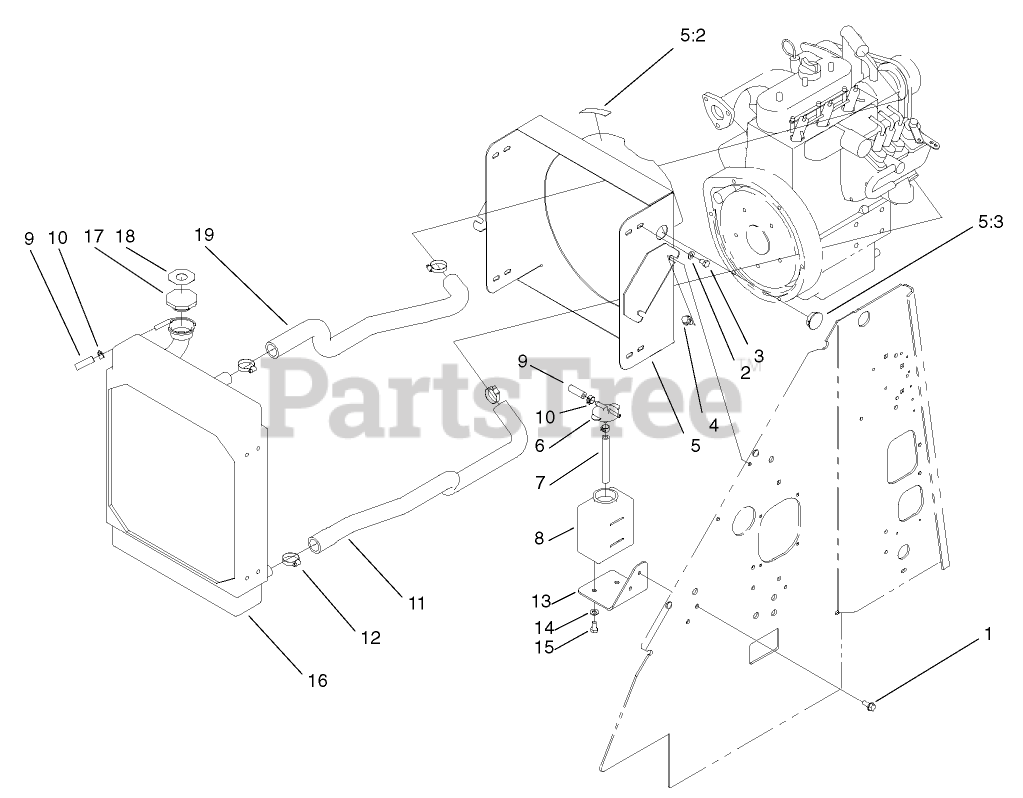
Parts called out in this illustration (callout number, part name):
1	SCREW-HWHTF
2	WASHER-FLAT
3	SCREW-HH
4	SCREW-HWHTF
5	MOUNT-RADIATOR
5:2	DECAL-WARNING, FAN
5:3	PLUG-HOLE
6	CAP-TANK, OVERFLOW
7	HOSE-FUEL
8	TANK-OVERFLOW
9	HOSE-FUEL
10	CLAMP-HOSE
11	HOSE-RADIATOR, LOWER
12	CLAMP-HOSE
13	MOUNT-TANK, OVERFLOW
14	WASHER-PLAIN
15	BOLT
16	RADIATOR
17	CAP-RADIATOR
18	DECAL-CAP, RADIATOR
19	HOSE-RADIATOR, UPPER
